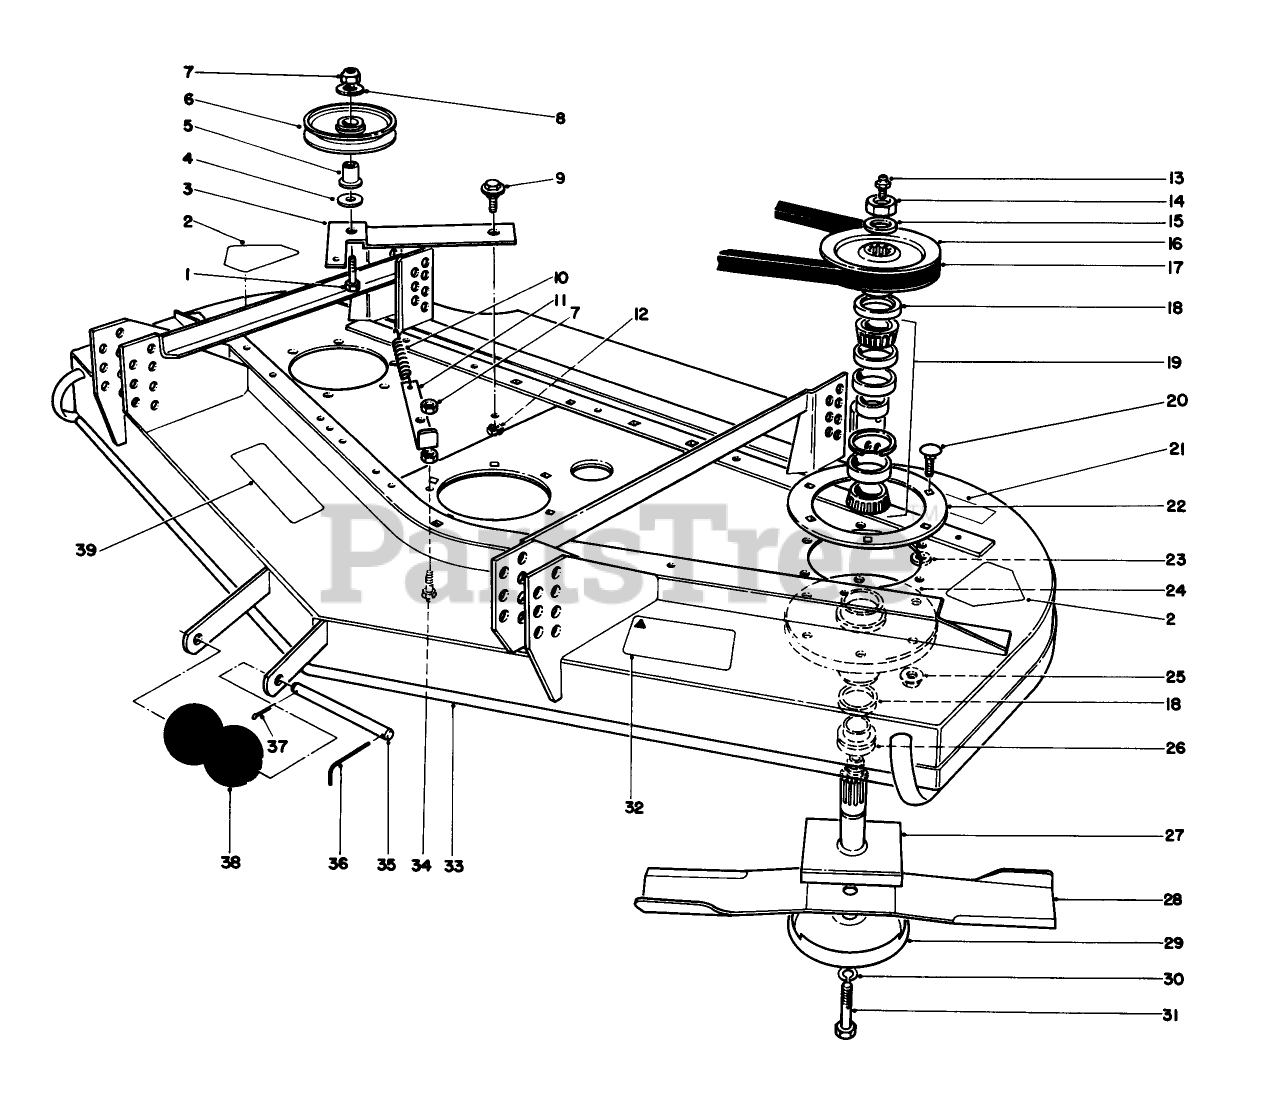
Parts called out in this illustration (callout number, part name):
1	SCREW-HH
2	DECAL-DANGER
5	BUSHING-PULLEY
6	PULLEY-IDLER
7	NUT-LOCK, SIDE
8	WASHER-FLAT
9	SCREW-SHOULDER
10	SPRING-EXTENSION, DECK
12	NUT-LOCK, NI
13	FITTING-GREASE
14	NUT-HEX
15	WASHER
17	V-BELT, DECK
18	SEAL-OIL
19	BEARING ASM
20	SCREW-CARR
21	CAUTION DECAL (BLADE)
23	WASHER-FLAT
25	NUT-HF
26	SPACER
27	SHAFT
30	WASHER-LOCK
31	SCREW-BLADE
34	SCREW-HH
35	SHAFT-ROLLER
36	PIN-SPECIAL
37	PIN-COTTER
38	ROLLER
